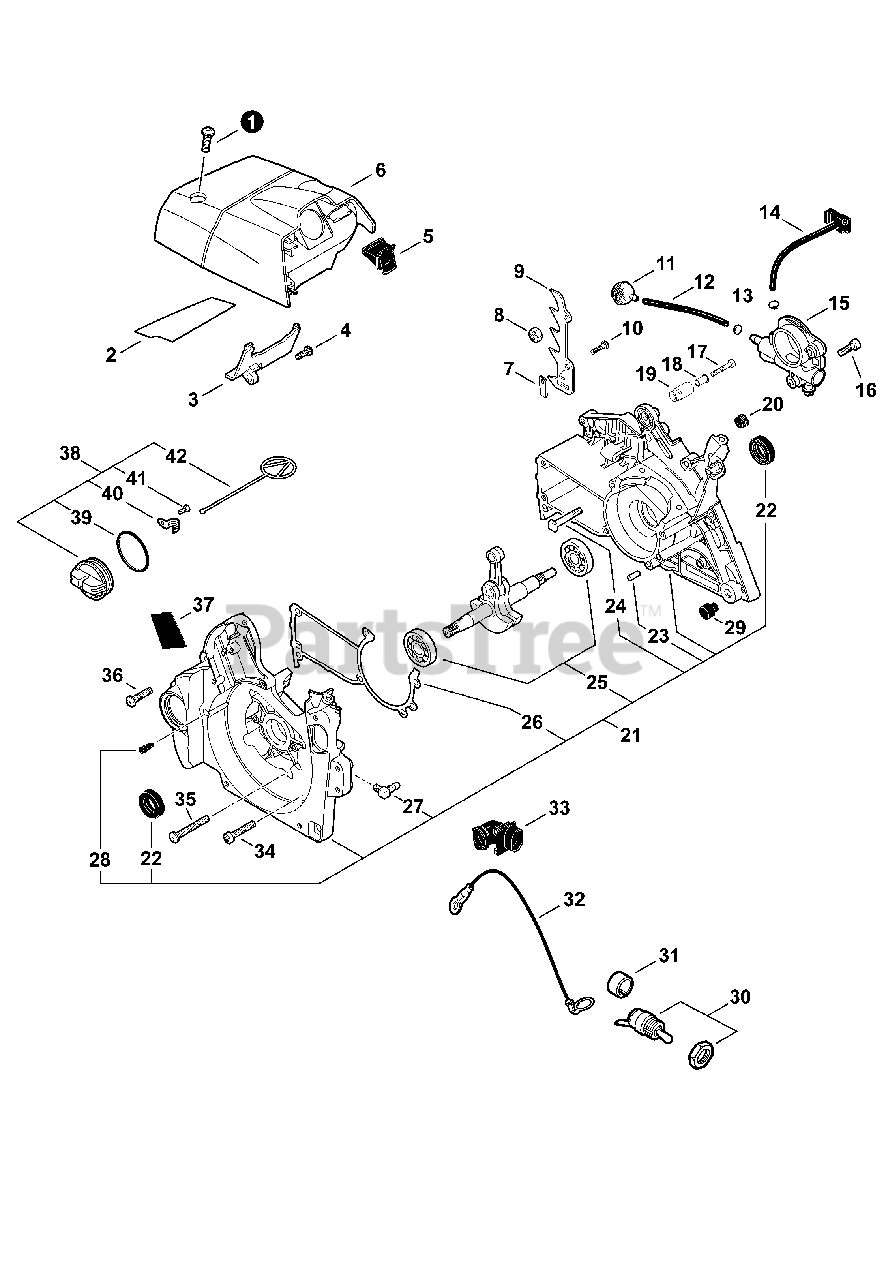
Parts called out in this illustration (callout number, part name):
1	BOLT, TORX 5
2	WASHER,SQUARE
3	GUIDE,AIR
4	BOLT, TORX 5
5	PIPE, INTAKE
6	COVER,CYLINDER
8	NUT, LOCK 5
10	BOLT, TORX 5
11	STRAINER, OIL
12	PIPE, OIL 3×6×210
14	PIPE
15	AUTO-OILER ASSEMBLY
16	BOLT, TORX 4
17	BOLT, TORX 5
18	COLLAR,5
19	CATCHER,CHAIN
20	GROMMET
21	CRANK CASE SET
22	SEAL,OIL 15
23	PIN, DOWEL
24	BOLT,8
25	BEARING BALL
26	GASKET,CRANKCASE
28	VALVE, CHECK
29	CUSHION
30	SWITCH, ON OFF
31	CASE,SWITCH
33	PIPE, INTAKE
34	BOLT, TORX 5
35	BOLT, TORX 5
36	BOLT, TORX 5
38	CAP, OIL
39	O-RING 28
40	RETAINER, LINK
41	SCREW 3×8
42	LINK
